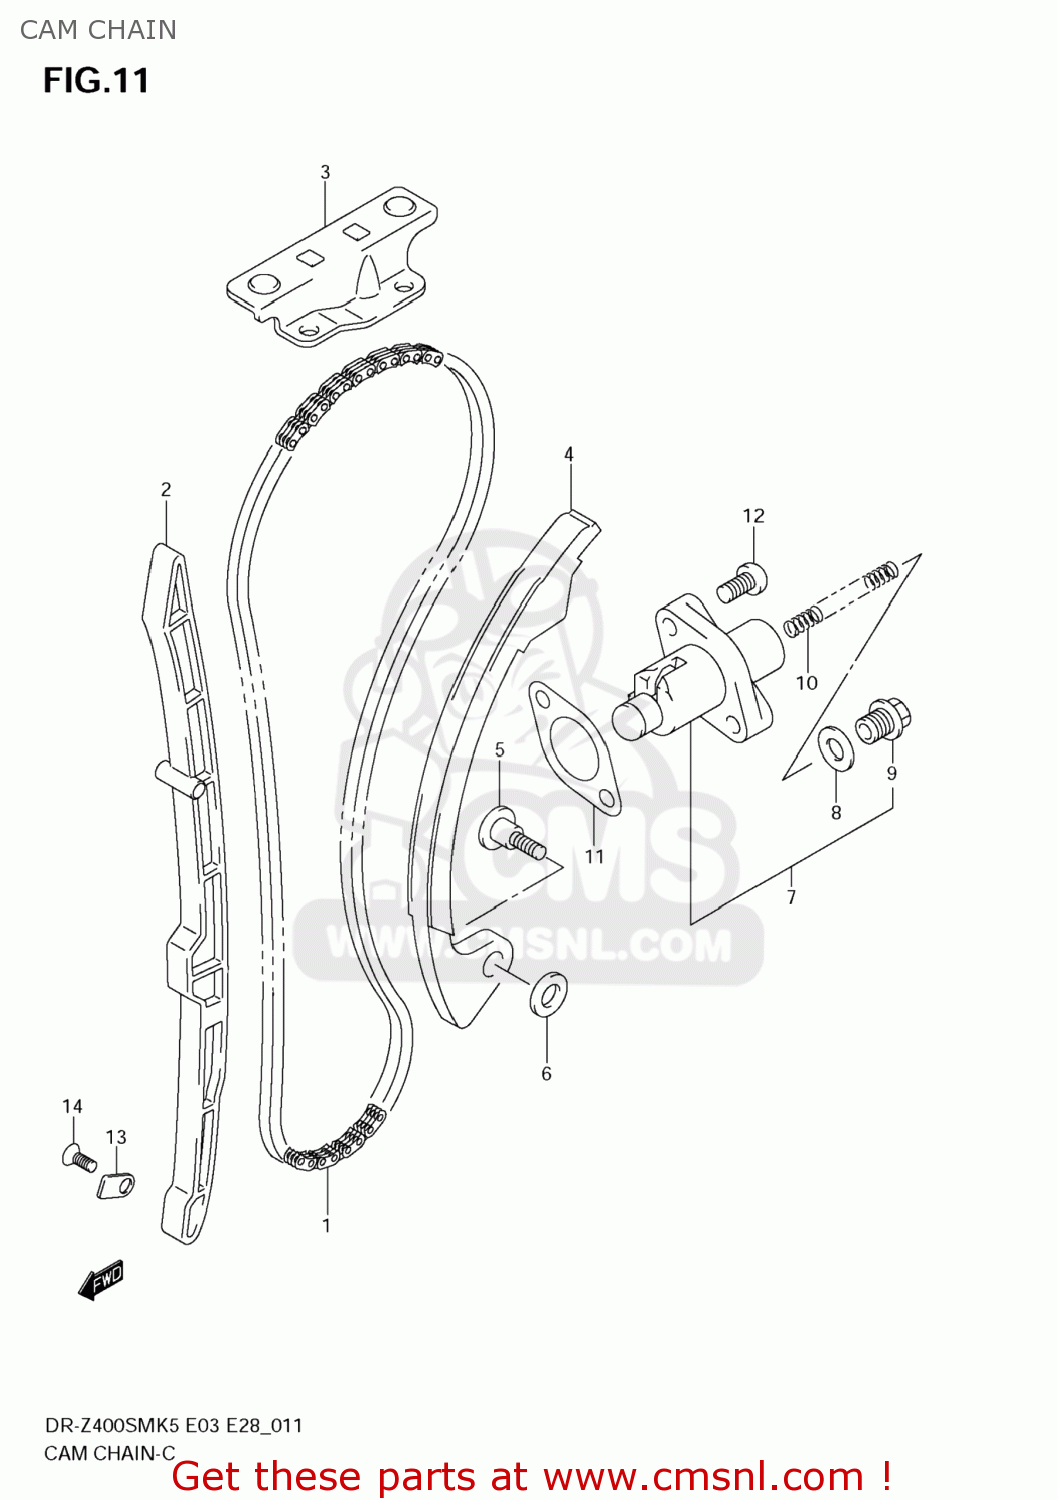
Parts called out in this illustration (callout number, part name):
1	CHAIN,CAMSHAFT DRIVE
2	GUIDE,CAM CHAIN NO.1
3	GUIDE,CAM CHAIN NO.2
4	TENSIONER,CAM CHAIN
5	BOLT,CAM CHAIN TENSIONER
6	WASHER
7	ADJUSTER ASSY,TENSIONER
8	GASKET,TENSIONER ADJUSTER (NAS)
9	PLUG,FR TENSIONER ADJ
10	SPRING
11	GASKET,TENSIONER ADJUSTER (NAS)
12	BOLT
13	RETAINER,CAM CHAIN GUIDE NO.1
14	SCREW(6X12)
